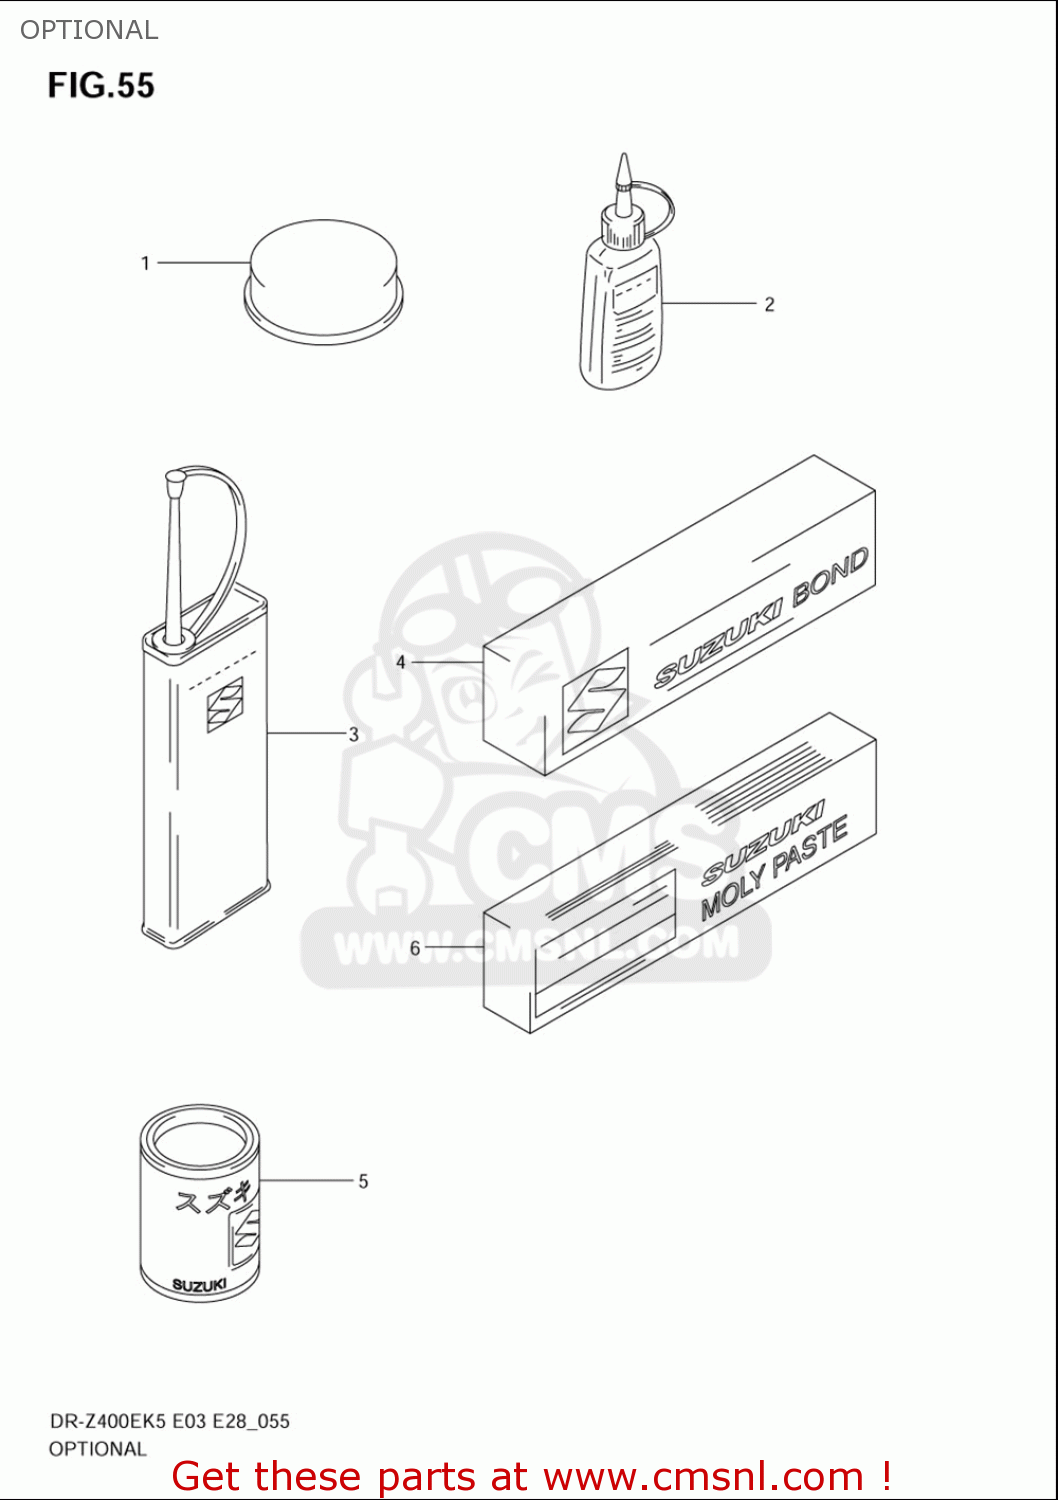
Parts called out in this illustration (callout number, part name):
1	GREASE,PBC FOR BRK PAD 20G
2	THREAD LOCK NO.1342
3	THREAD LOCK NO.1401 CLEAR 200G
4	LIQUID GASKET 1
5	GREASE(C)EP2 LITHIUM 150G
6	SUZUKI MOLY PASTE
